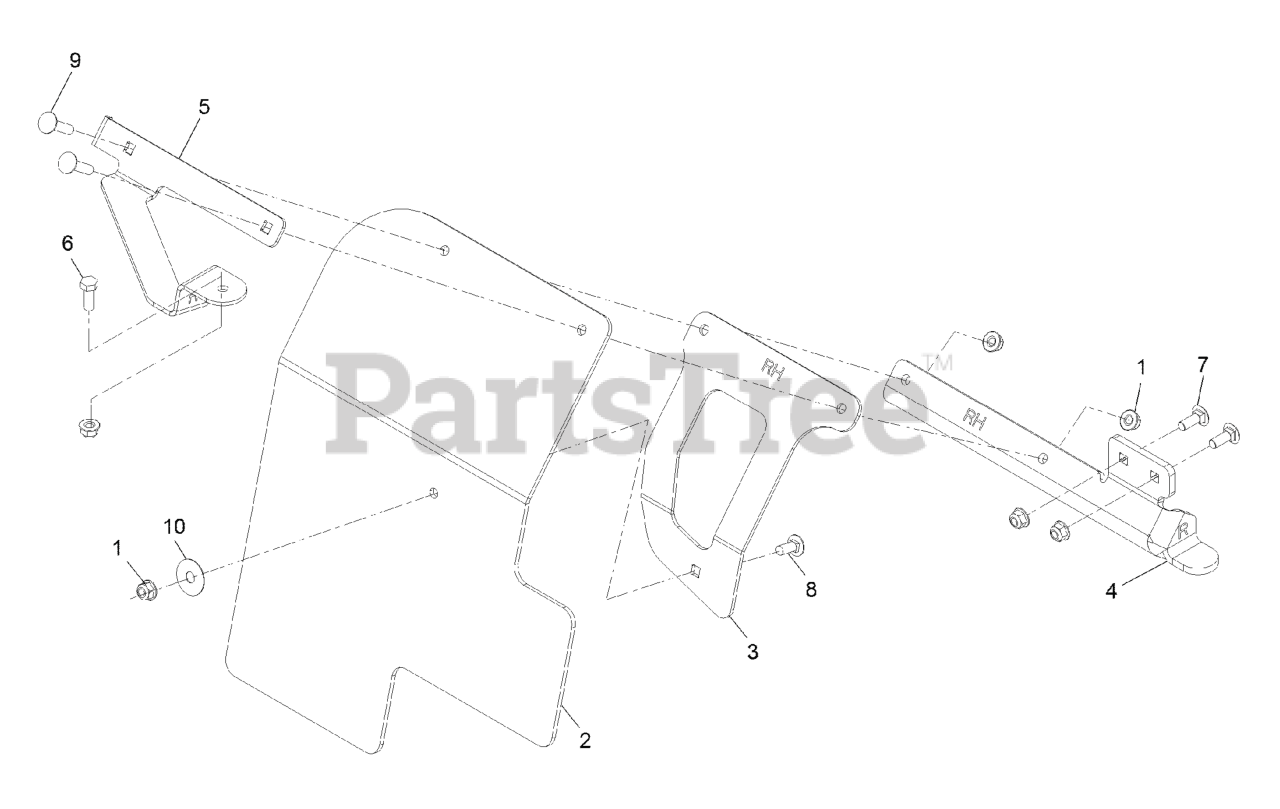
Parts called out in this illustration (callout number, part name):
1	NUT-HF, NI
2	RH MUD FLAP
5	SUPPORT, RH MUD FLAP
6	SCREW-HH
7	SCREW-CARR
8	SCREW-CARR
9	Bolt-Carriage 5/16-18 X 1 1/4
10	WASHER-PLAIN
